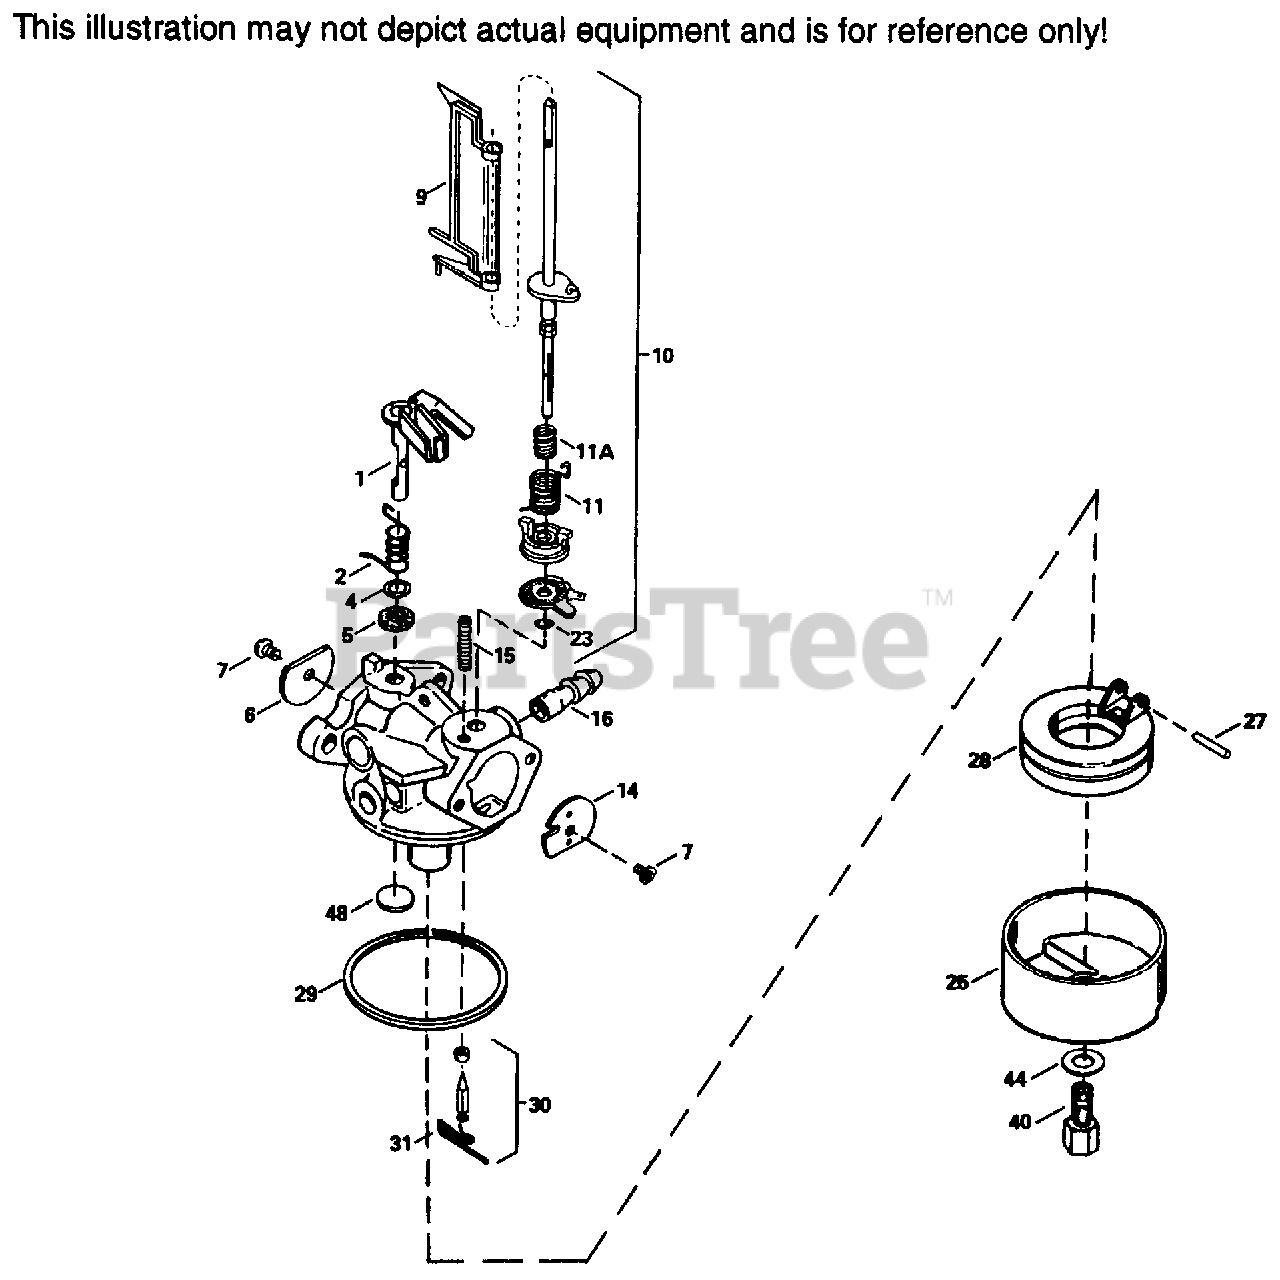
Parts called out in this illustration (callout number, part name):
1	Throttle Shaft & Lever Assembly
2	Throttle Return Spring
4	Dust Seal Washer
5	Dust Seal (Throttle)
6	Throttle Shutter
7	Shutter Screw
9	Air Vane
10	Choke Shaft & Lever Assembly
11	Choke Return Spring
11A	Compression Spring
14	Choke Shutter
15	Choke Positioning Spring
16	Fuel Fitting
23	"O" Ring
25	Float Bowl
27	* Float Shaft
28	Float
29	* Float Bowl "O" Ring
30	* Inlet Needle, Seat & Clip (Incl. 31)
31	Spring Clip
40	* Main Adj. Screw Ass'y Incl. 41 thru44
41	High Speed Mixture Screw "O" Ring
42	High Speed Mixture Screw Washer
43	High Speed Mixture Screw Tension Spri ng
44	* Bowl Nut Washer
48	* Welch Plug, Atmospheric Vent
60	Repair Kit Incl. items marked PK inn otes
